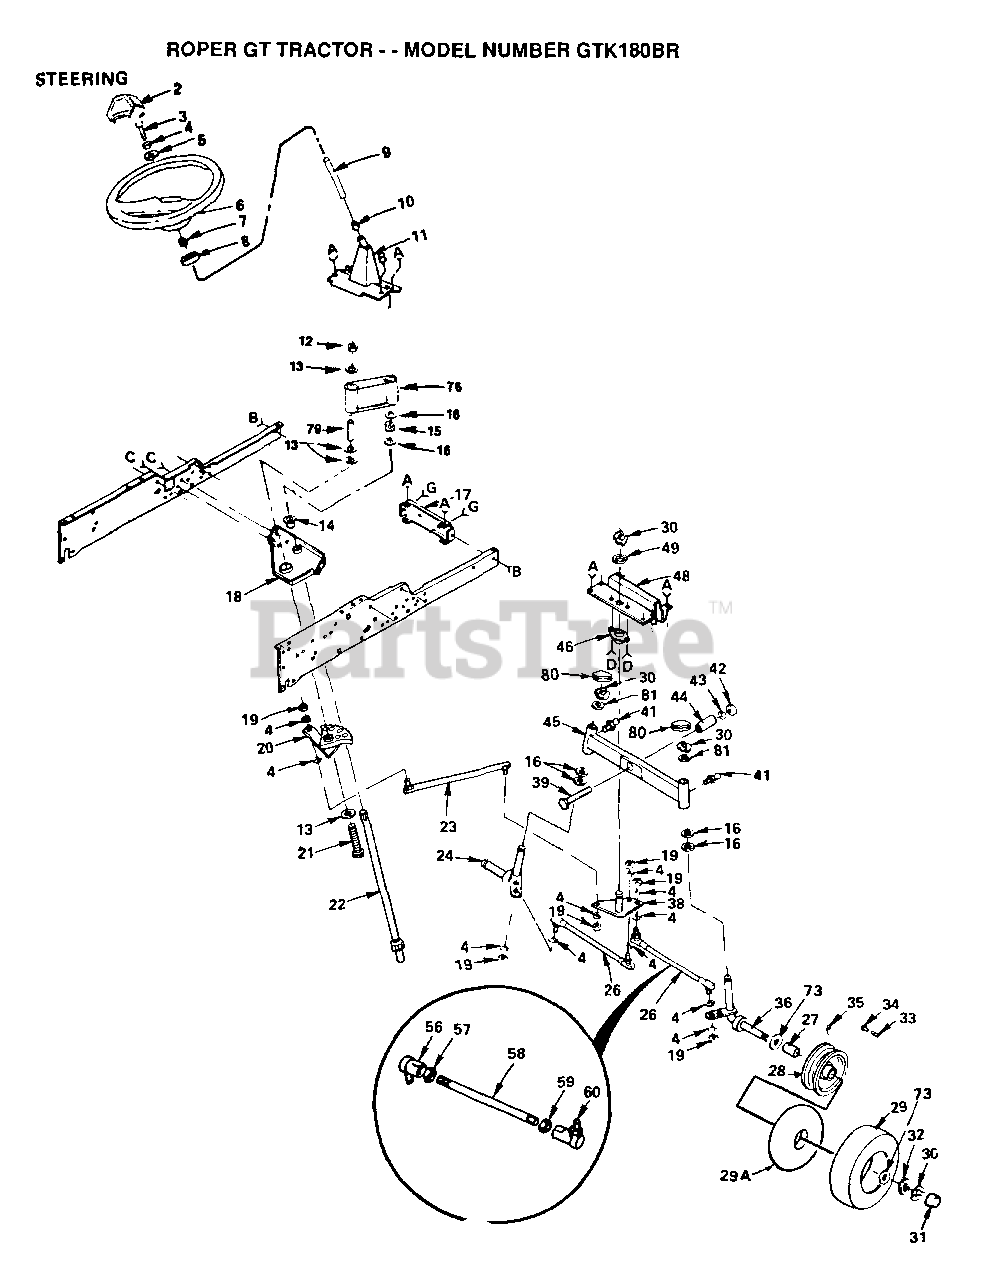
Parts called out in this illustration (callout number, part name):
2	INSERT STEERING
3	BOLT
4	LOCKWASHER
5	WASHER T
7	ADAPTER LT
9	TUBE
10	"T, BEARING"
11	SUPPORT ASSY T
12	NUT LTV
13	WASHER GT
14	"FLANGE GT, BEAR."
15	KLIP RING
16	WASHER .T
17	FRAME BRACKET GT
20	SECTOR T
21	BOLT T
22	SHAFT STEERING GT
23	LINK.DRAG.T
27	"FLANGE, BEARING"
29A	TUBE.16X6.5/7.5-8
30	RING
31	HUB CAP
32	WASHER
33	VALVE CAP
34	VALVE STEM LT
35	FITTING LT
38	"T, BELLCRANK"
39	BOLT
41	ZERK M
42	NUT X
43	WASHER
45	FRONT AXLE T
48	AXLE BRACKET T
49	WASHER
57	NUT
58	ROD TIE
59	NUT
73	WASHER
76	COLLAR
79	TUBE T
80	CAP
81	WASHER
